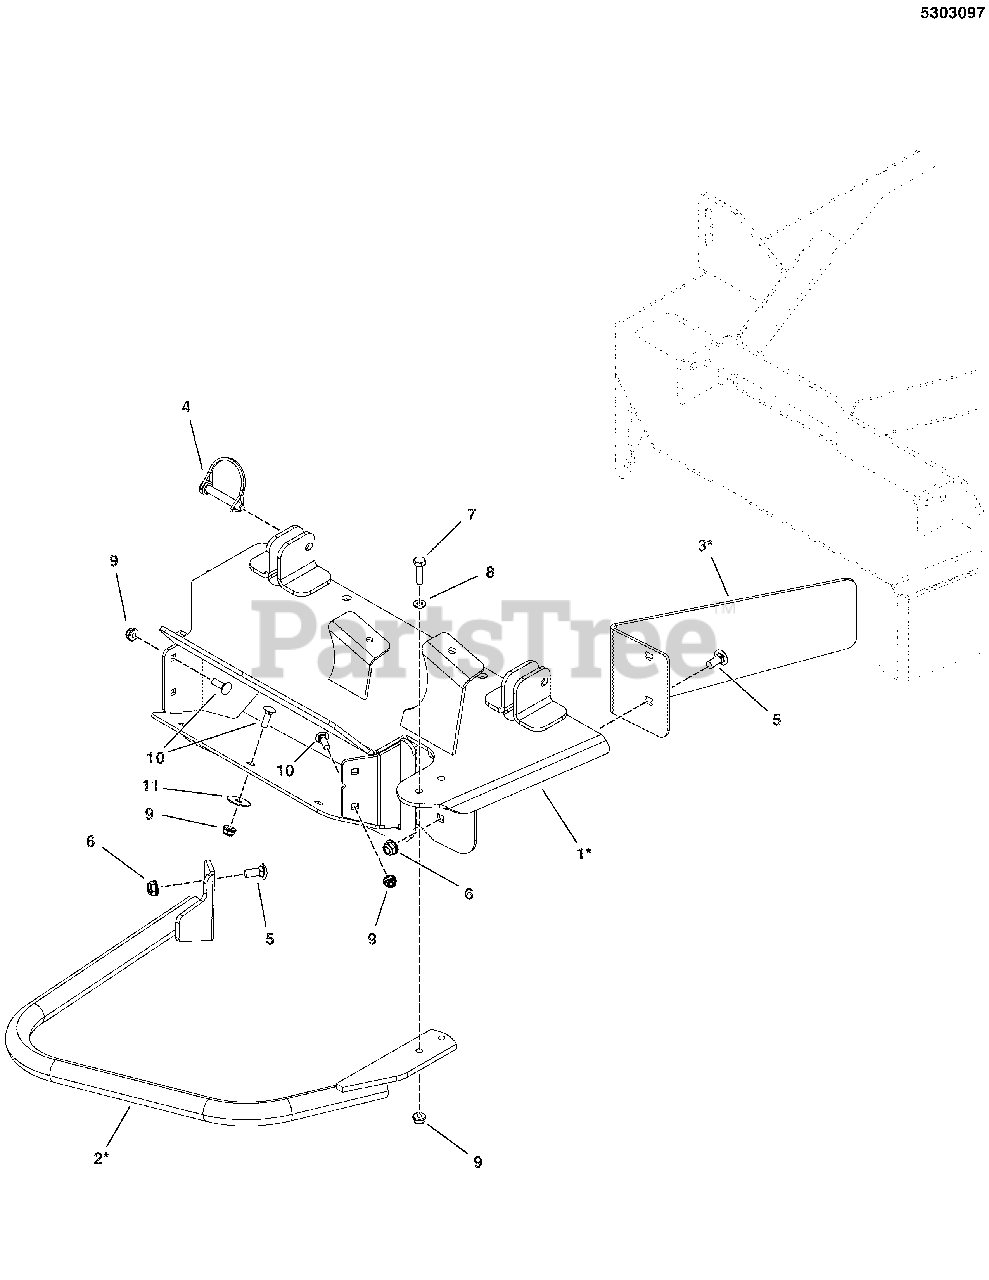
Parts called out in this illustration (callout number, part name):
3	DECK WEDGE, 52" - BLK
4	SNAPPERPIN, 5/16 X 2
5	BOLT, 5/16-18 X 3/4, CARRIAGE
6	NUT, 5/16-18 HEX NYLOCK FLANGE
7	BOLT, 1/4-20 X 1" GD5 CZ
8	WASHER, 1/4 SAE (5025154)
9	NUT, 1/4-20 HEX NYLOCK FLANGE (5025391)
10	BOLT, 1/4-20X.750, SQ
11	WASHER, 1/4 FENDER
